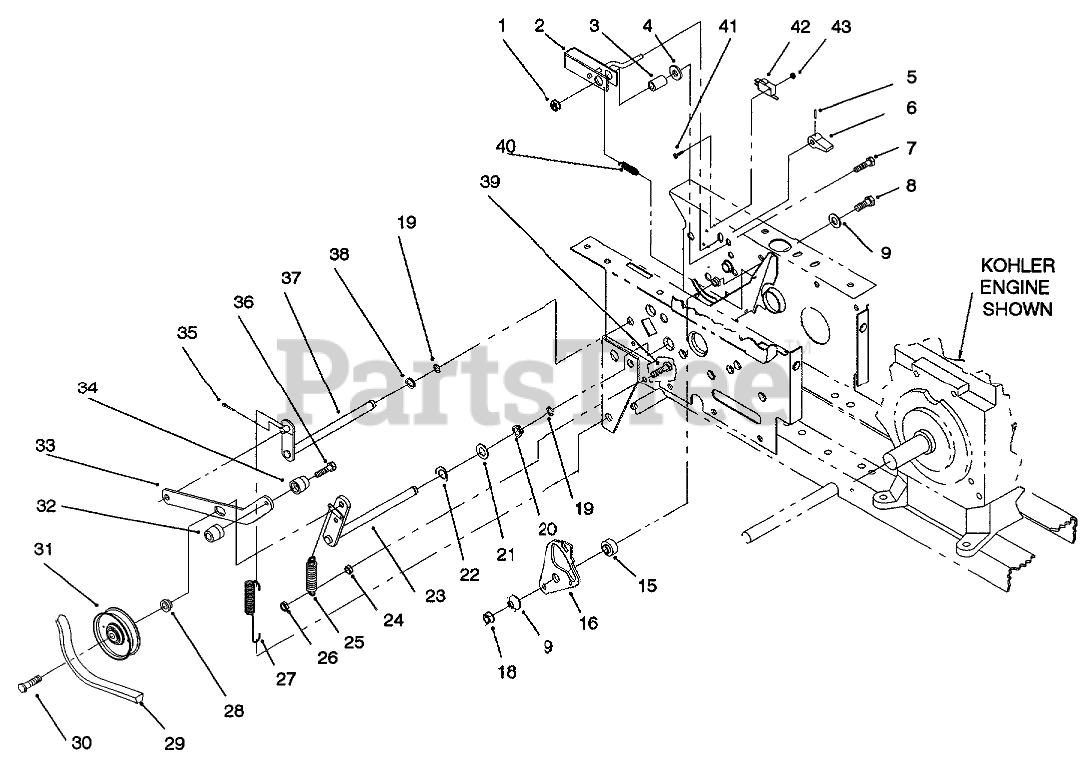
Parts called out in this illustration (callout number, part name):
1	NUT-HF
2	WLMT-BRAK (BLACK)
3	SPACER
4	WASHER-SPACER
5	PIN-SPIROL 3/32X5/8
6	KNOB-PARKING BRAKE
7	SCREW-HH
8	SCREW-HH
9	WASHER-FLAT
15	Spacer
16	PLATE-CAM (BLACK)
18	NUT-LOCK, NI
19	RING-RETAINING, EXTERNAL
20	BUSHING-FLANGED
21	SHIM-WASHER
22	CURVED-SPRING WASHER
23	WLDMT-IDLER ARM
24	NUT-HEX
25	SPRING-EXTENSION
26	NUT-LOCK, NI
29	BELT-V
30	SCREW-HH
31	PULLEY-IDLER
39	SCREW-HH
40	EXTENSION-SPRING
41	SCREW-PPH
42	SWITCH
43	NUT-HEX
